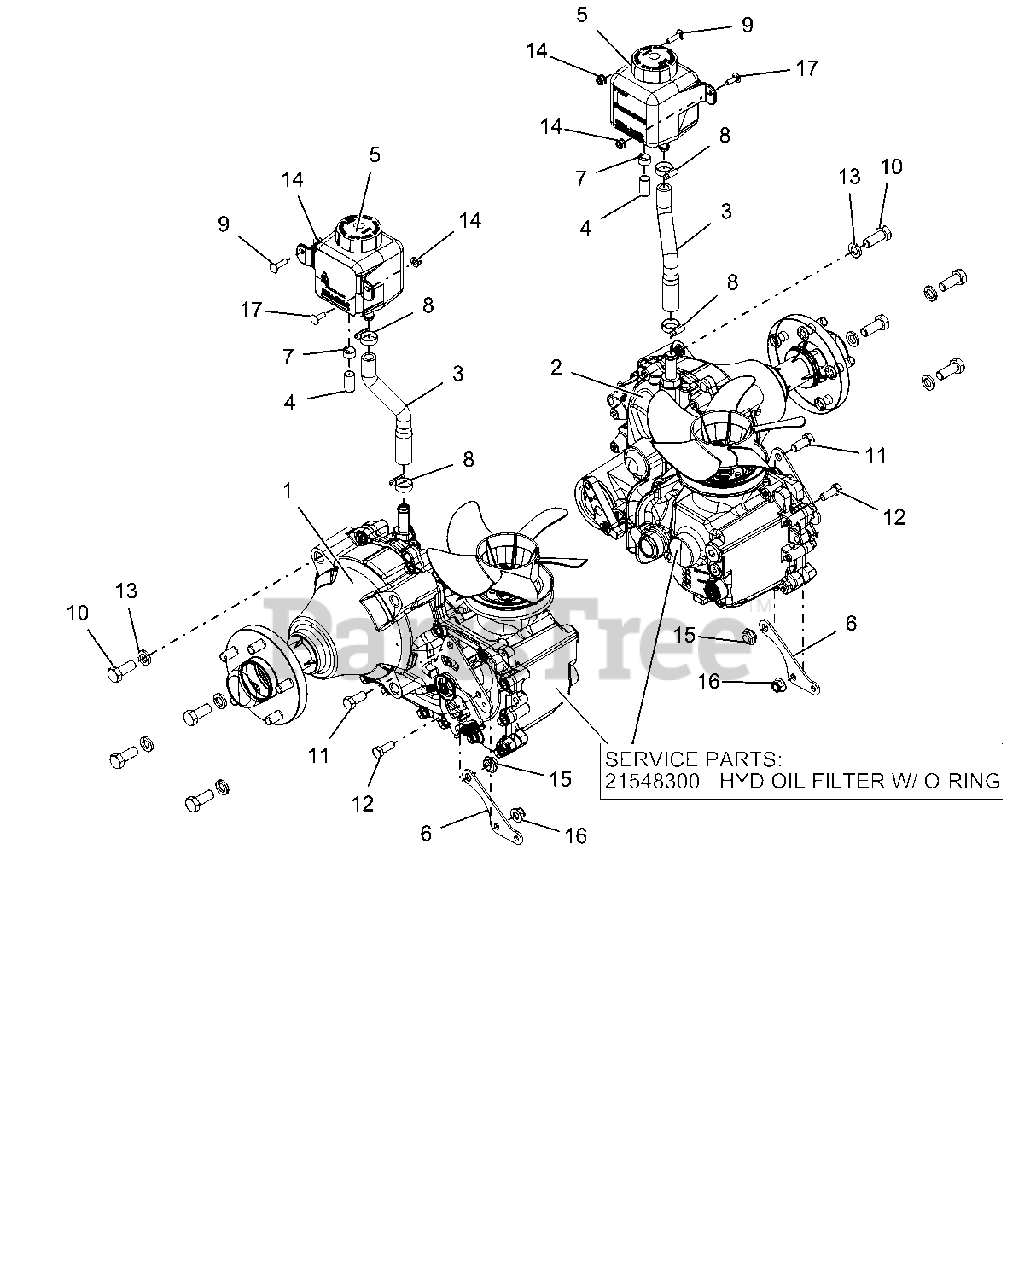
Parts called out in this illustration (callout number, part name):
1	TRANS, R.H. HG ZT-5400
1	HYDRO OIL FILTER W/ O-RING
2	TRANS, LH HG ZT-5400
2	HYDRO OIL FILTER W/ O-RING
3	HOSE, PT200/400 TRANSAXLE OVERFLOW
4	CAP, .50 BARBED FITTING
5	TANK, HYDRO OVERFLOW 700ML
6	BRKT, DRIVE CONTROL LINKAGE MTG
7	CLAMP, HOSE
8	CLAMP, .88 DIA HOSE
9	BLT-RDHDSQNK .25-20X1.00 G5 YWZC
10	BLT-HEX .50-13X1.25 GR5 YWZC
11	BLT-HEX .44-14X1.00 GR5 YWZC
12	BLT-HEX .38-16X1.00 GR5 YWZC
13	WSHR-LK .50X.125 REG YWZC
14	NUT-LK-NYL-FLG .25-20 YWZC
15	NUT-LK-NYL-FLG .44-14 YWZC
16	NUT-LK-NYL-FLG .38-16 YWZC
17	BLT-RDHDSQNK .25-20X.75 G5 YWZC
